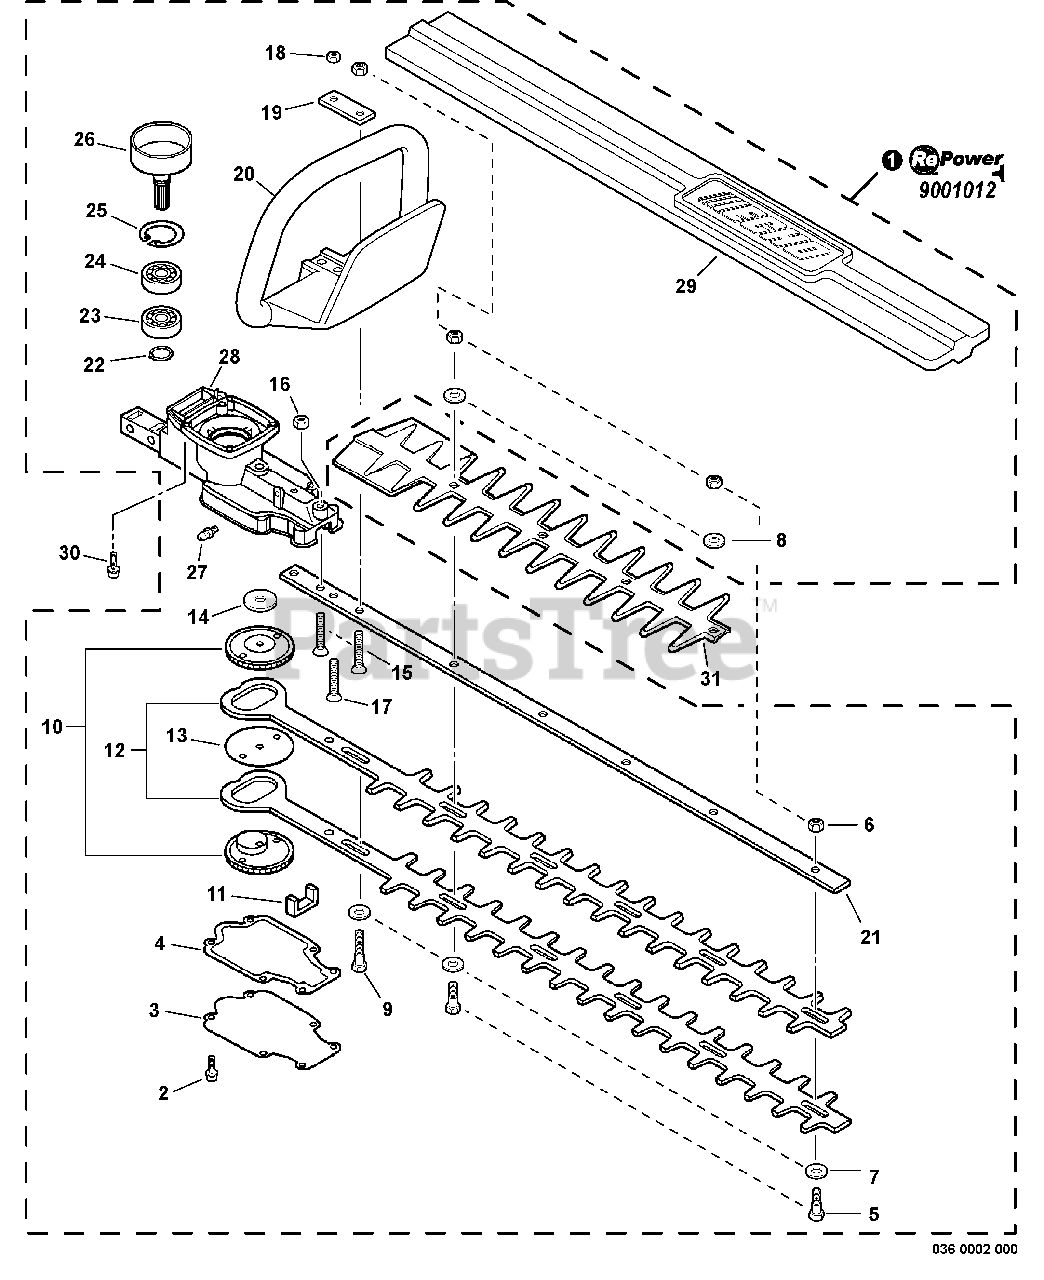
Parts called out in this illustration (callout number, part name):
1	GEAR CASE ASSY
2	SCREW - 4X12
3	LID, GEAR CASE
4	GASKET, GEAR CASE
5	BOLT - 6X18
6	LOCKNUT - 6
7	WASHER - 6
8	WASHER - 6
9	BOLT - 6X35
10	GEAR - SPUR
11	SEAL, FELT
12	BLADE, TRIMMER
15	SCREW - 6X30
16	LOCKNUT - 6
17	SCREW - 5X30
18	LOCKNUT - 5
20	HANDLE - FRONT
21	SUPPORT, BLADE
22	RING, RETAINING - 14
23	BEARING, BALL - 6202
24	BEARING, BALL - 6202
25	RING, RETAINING - 35
26	DRUM, CLUTCH
27	FITTING, GREASE
28	CASE, GEAR
29	COVER, BLADE - 20" (50cm)
30	SCREW - 4X16
31	SHIELD, BLADE
